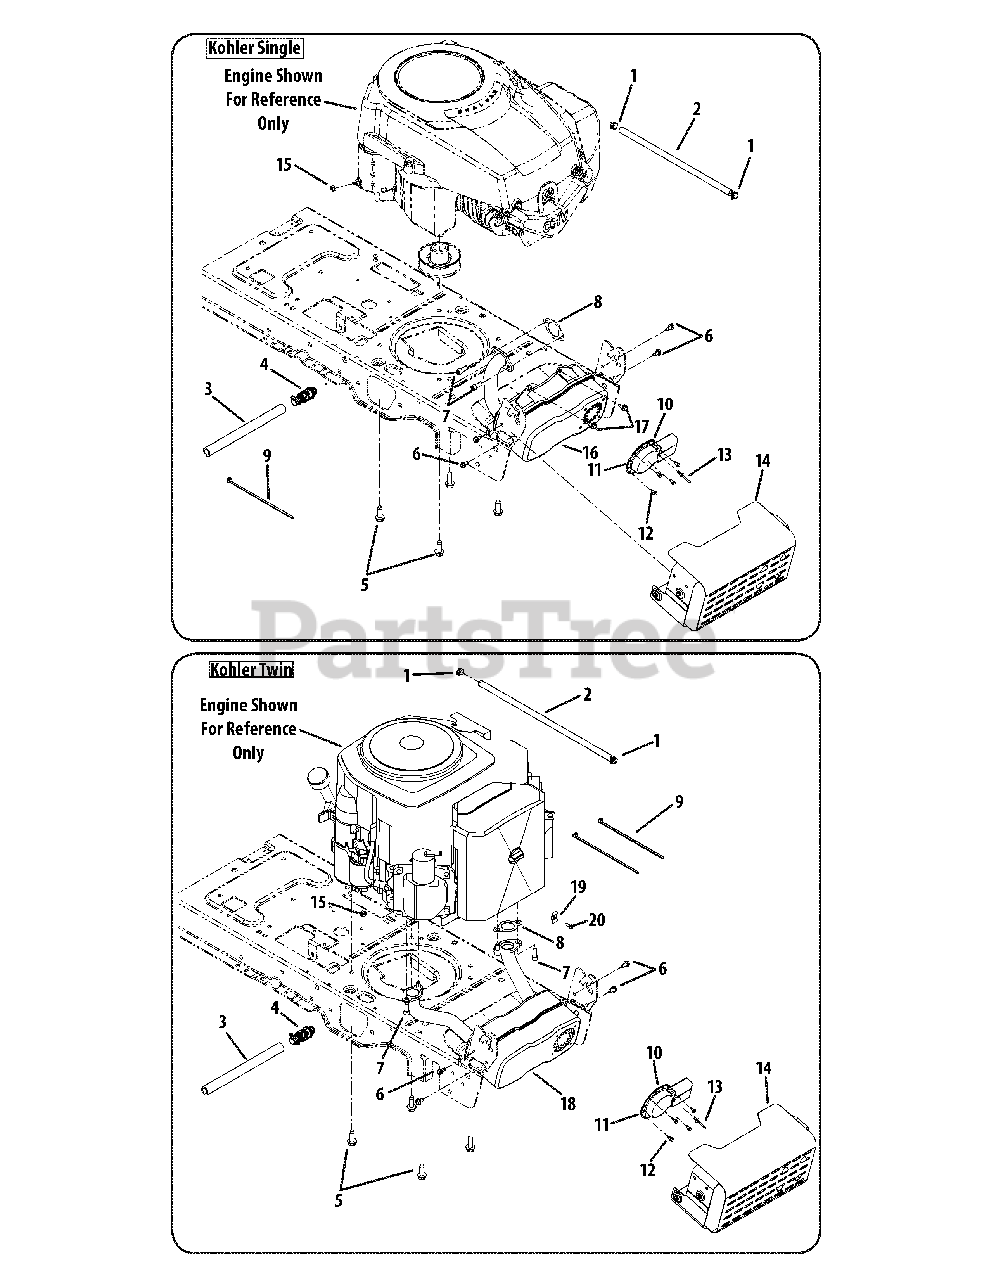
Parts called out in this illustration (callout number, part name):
1	Hose Clamp
3	Extension Hose
5	Hex Washer Screw, 3.8-16 x 1.00
6	Hex Washer Screw, 1.4-20 x .500
7	Screw, 5.16-18 x .750
8	Exhaust Gasket
9	Cable Tie, 3.16 x .05 x 7.4
10	Muffler Deflector
11	Long Muffler Deflector
12	Hex Washer Screw, #8-18 x .500
13	Rivet, .188 x .300
14	Muffler Shield Assembly
15	Sems Nut, 1.4-20
16	Kohler Single Muffler
17	Hex Washer Screw, 1.4-20 x .625
18	Kohler Twin Muffler
19	Dual Conduit Clamp
20	Tap Screw, M5 x .8
